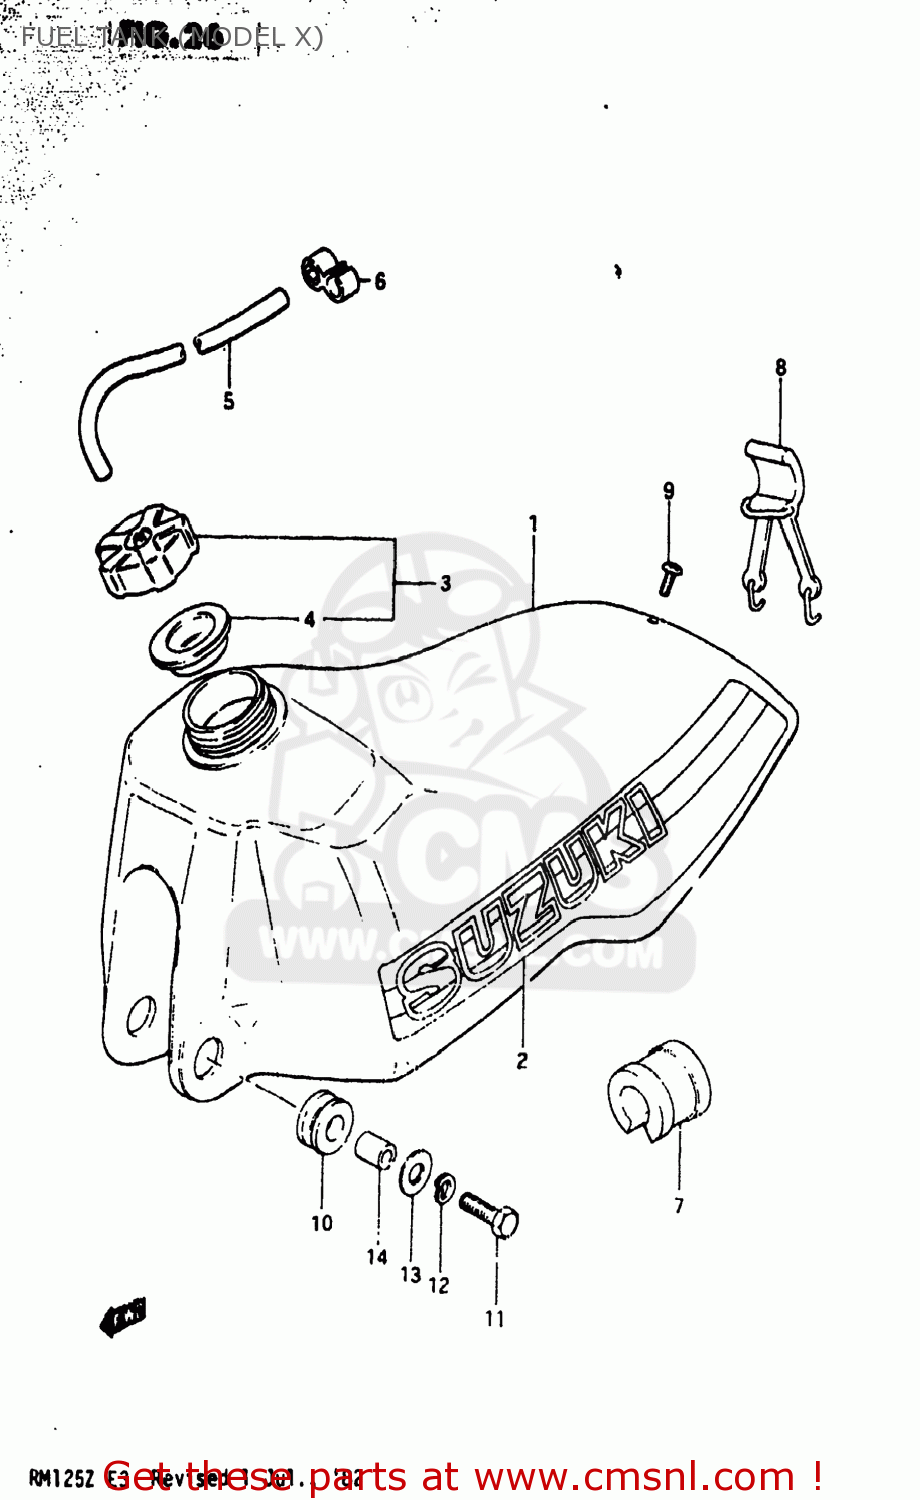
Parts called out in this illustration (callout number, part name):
1	TANK ASSEMBLY,FUEL
2	TAPE SET,FUEL TANK
3	CAP SET,FUEL TANK
4	GASKET,FUEL TANK CAP (NAS)
5	HOSE
6	CLAMP,BREATHER HOSE
7	CUSHION,FUEL TANK UPR
8	BAND,FUEL TANK,REAR
9	SCREW (6X15)
10	CUSHION
11	BOLT (8X30)
12	LOCK WASHER
13	WASHER (8.5X29X1.6)
14	SPACER (8.8X12X15.5)
